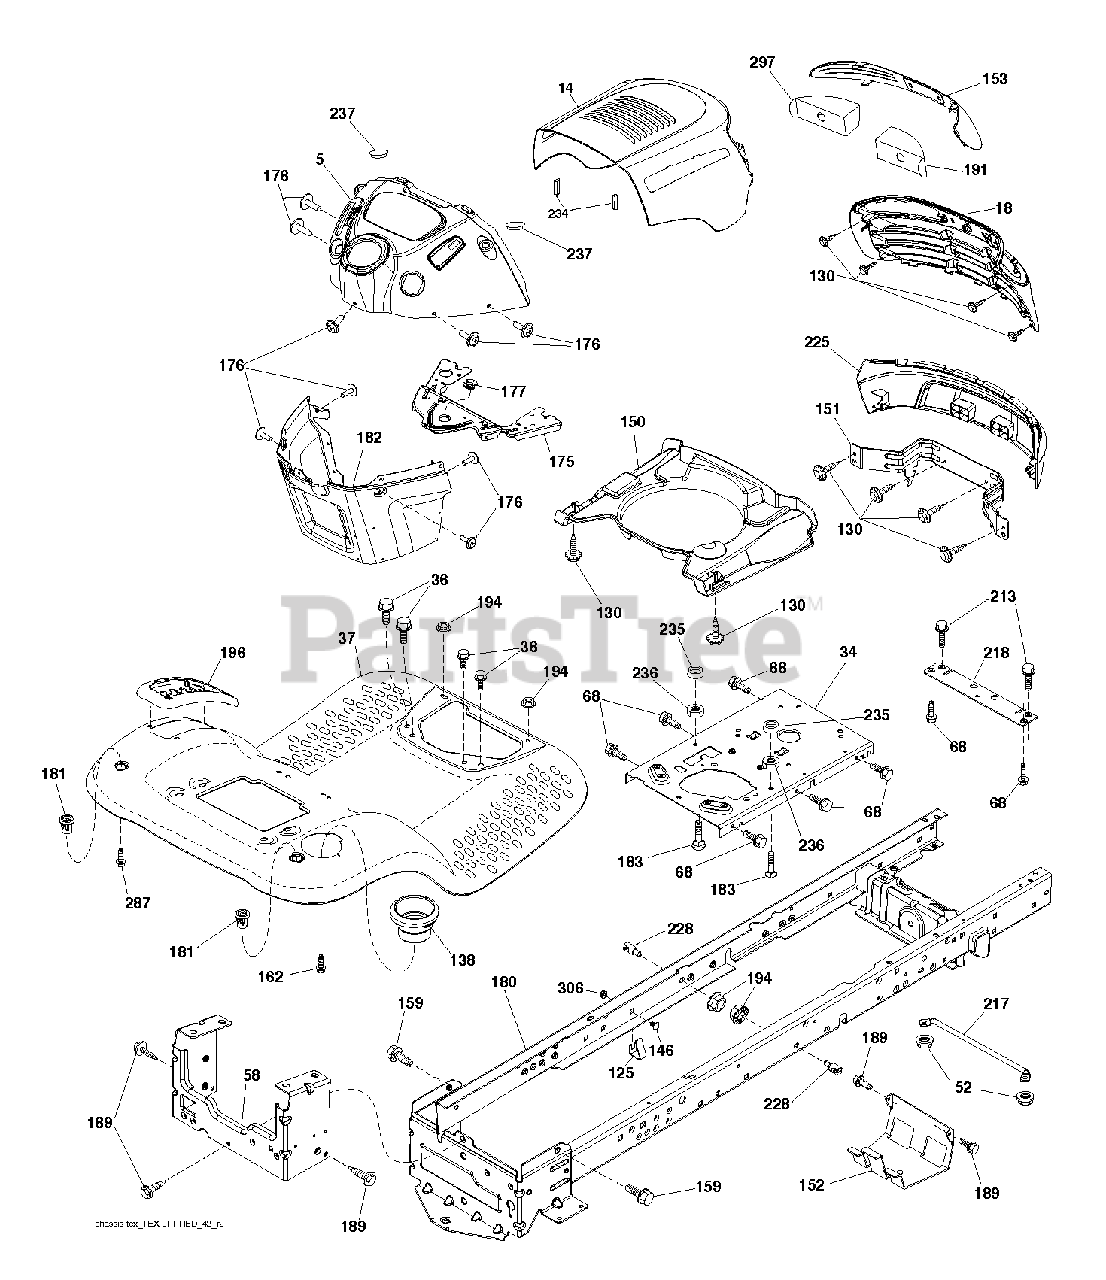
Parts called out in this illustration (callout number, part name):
5	DASH.PRED.LT.CC.ICY.N/SRV.BLK
14	HOOD.PREDATOR.LT.U-FORM.TOPVN
18	GRILLE.SVC.BASE.PREDATOR.LT428
34	PLATE.ENGINE.WELDED.CHASSIS
36	SCREW 5/16"
52	LOCKNUT
58	DRAWBAR UPPER 2PC SMALL FENDER
68	SCREW LT
125	CLIP.FUEL.LINE
130	SCREW.#10 X 0.750.BOS (2 2)
138	CUPHOLDER.TL.TEX.BLACK
146	BOLT.RDHD.SHT.SQNK.3/8-16X5/8
150	DUCT.AIR.TOP.VENT.PREDATOR.LT
151	BRACKET.PIVOT.ALPHA.LT
152	SHIELD.BROWNING.W/TEX
153	LENS.PREDATOR.LT
159	SCREW, 3/8-16X3/4
162	SCREW.HI-LO.CONSOLE
175	CROSSMEMBER.LT
176	SCREW.#10-24X5/8.RN.QU
177	BUSHING STEERING
180	CHASS.WLDMNT.TL.12GA/2P.48/54
181	FEND/FTRST.PCH.CPH.NFW
182	DASH.LOWER.PREDATOR LT
183	BOLT.5/16-18X1-1/4 FULL THD
189	SCREW
191	INSERT.REFLECT.PREDATOR.LT.RH
194	NUT LOCK HEX FLANGE 5/16-18
196	CONSOLE.DECK.LIFT.TLT.BLK
213	BOLT
217	ROD.PIVOT.HOOD
218	X-PIECE.HOOD.STOP.NON/
228	STUD.FASTNER.W/ANTI-ROTATE
234	BUMPER.HOOD.TEX.HUSQVARNA
235	SPACER FENDER
236	NUT.CENTERLOCK.5/16-
237	PLUG.MOUNT.CARGO.BLK
287	SCREW 1/4X20
297	REFLECTOR.INSERT.PRED.LH.LT
306	NUT LOCK FLG 3/8-16 UNC
